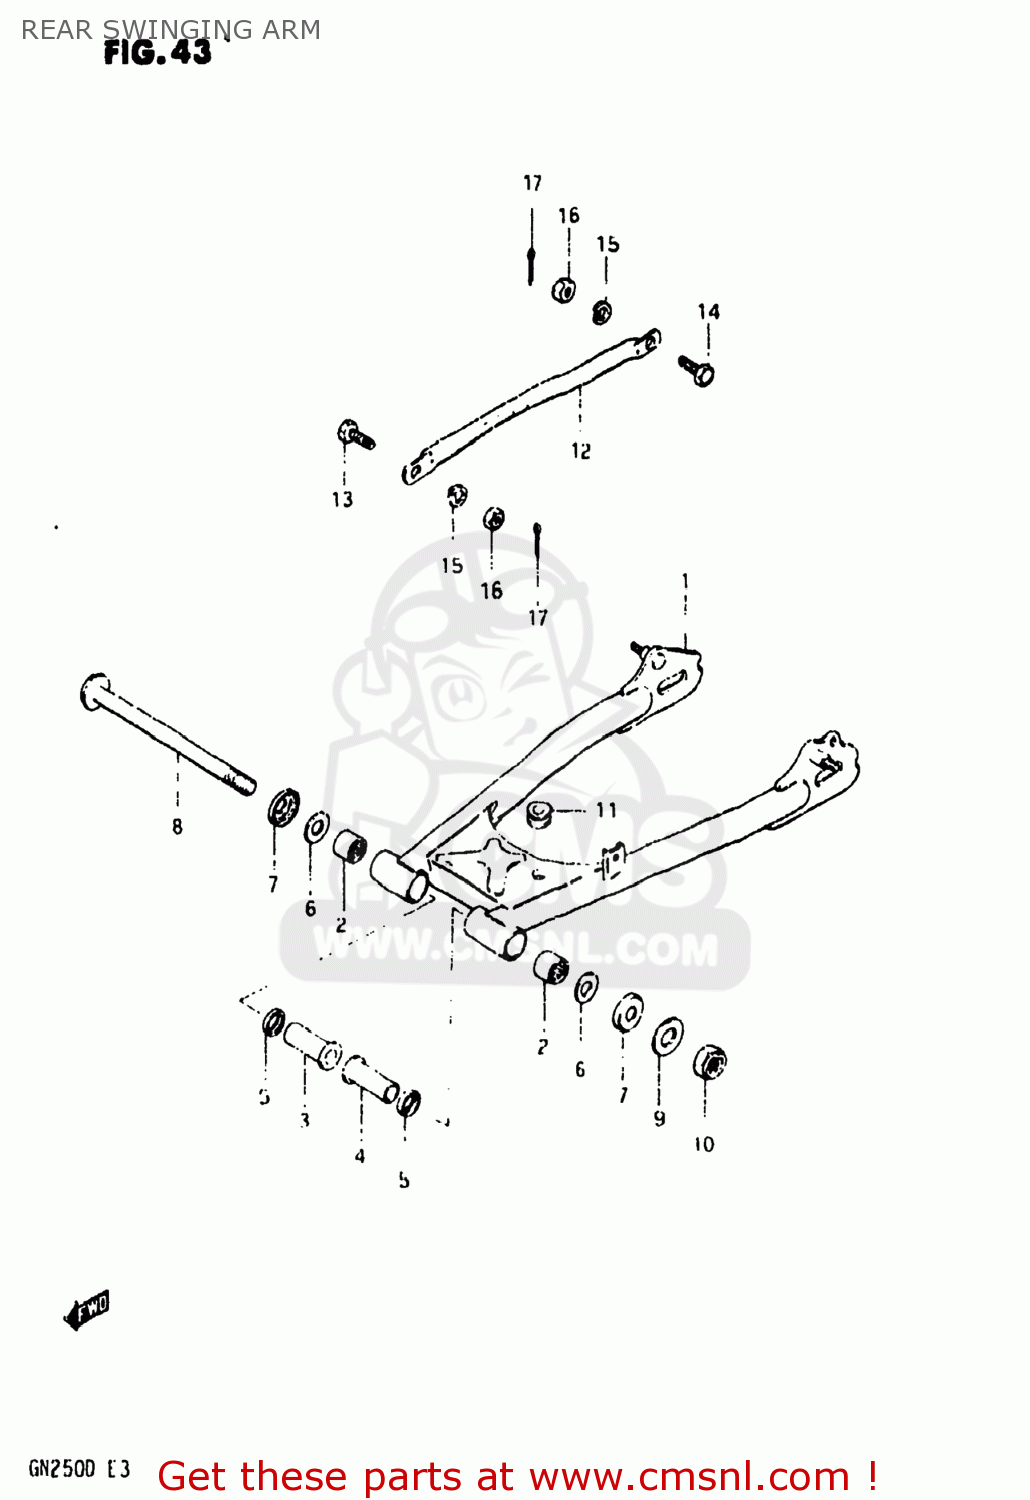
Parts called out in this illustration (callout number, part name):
1	SWINGINGARM ASSY,RR
2	BEARING(20X27X20)
3	SPACER,RR SWGARM PIVOT,R
4	SPACER,RR SWGARM PIVOT,L
5	SEAL,OIL(20X27X5)
6	WASHER
7	COVER,RR SWINGINGARM PIVOT
8	SHAFT,REAR SWING ARM
9	WASHER
10	NUT 14MM
11	CUSHION
12	TORQUE LINK,REAR
13	BOLT(8X22.5)
14	BOLT(8X26.5)
15	LOCK WASHER
16	NUT
17	PIN 20X20
